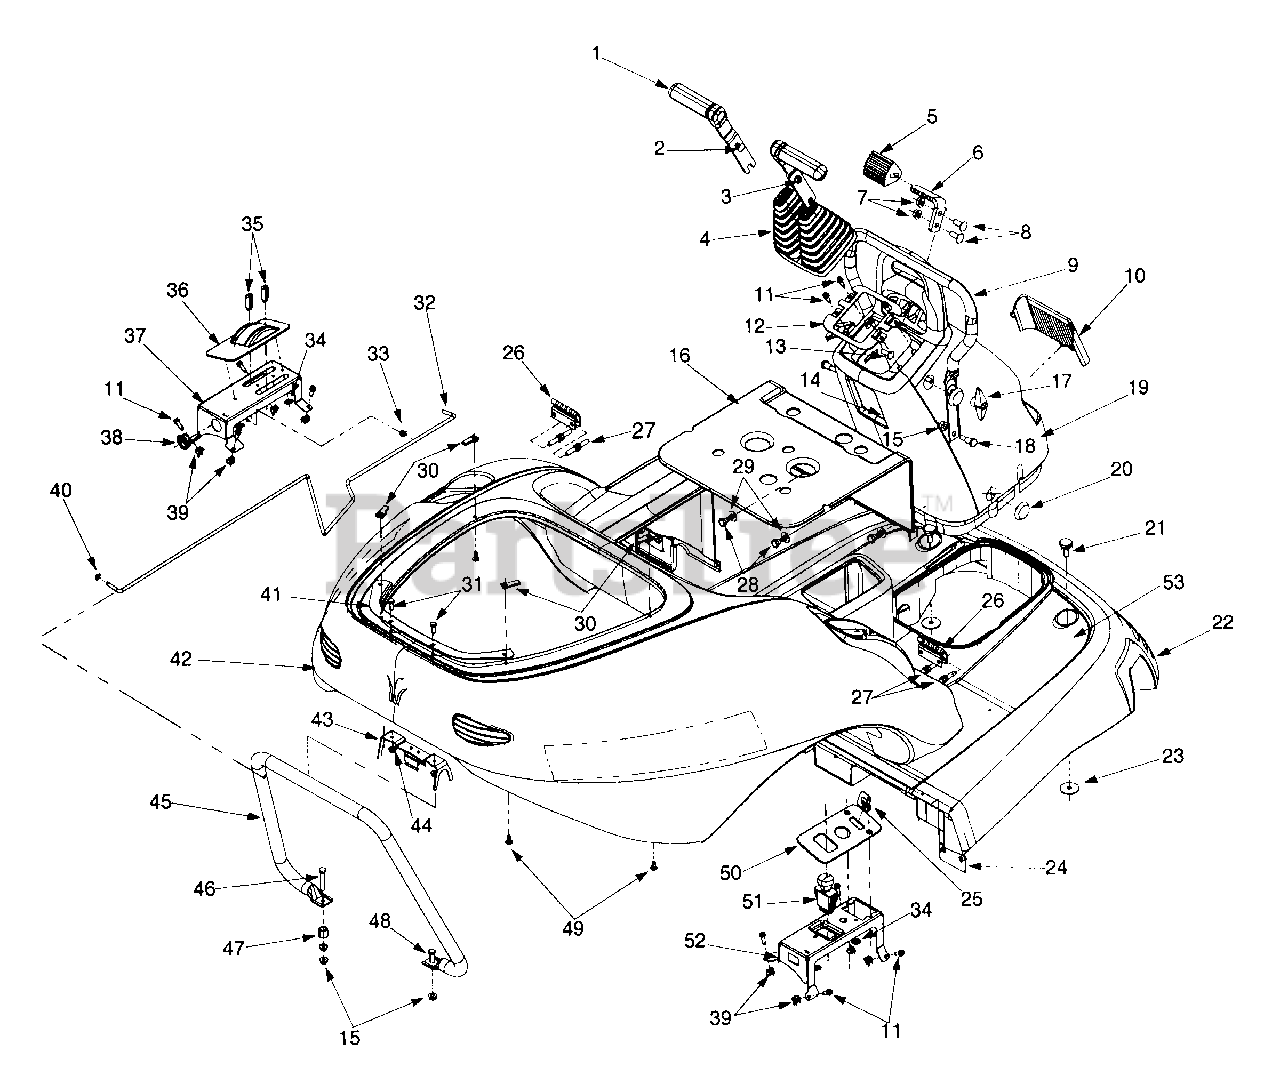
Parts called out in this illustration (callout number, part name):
1	Control Handle
2	Carriage Bolt 5/16-18 x .75
3	Flange Lock Nut 5/16-18
4	Control Bellow
8	Carriage Bolt 3/8-16
11	Hex Washer Screw 1/4-20 x .75
16	Seatbase Cover
17	Wingnut Knob Assembly 5/16-18
18	Shoulder Screw
21	Shoulder Screw 3/8-16 x .75
23	Flat Washer .406 ID x 1.5 OD
24	Body Plate Assembly
25	Key
26	Body Hinge
27	Hex Cap Screw 5/16-18 x 1.0
28	Shoulder Screw
29	Flat Washer .474 ID x .879 OD
30	U-Type Nut 1/4-20
31	Hex Cap Screw 1/4-20 x .75
32	Support Rod
33	Clip
34	Push Nut
35	Lever Knob
36	Control Panel Cover - LH
39	Retainer Nut 1/4-20
41	Latch Mounting Plate
42	Rear Body
43	Clip Spring Bracket Assembly
44	Lock Nut 1/4-20
48	Hex Cap Screw 5/16-18 x 1.0
49	Screw 1/4-20 x .625
50	Cover Panel - RH
51	Electric Switch PTO
